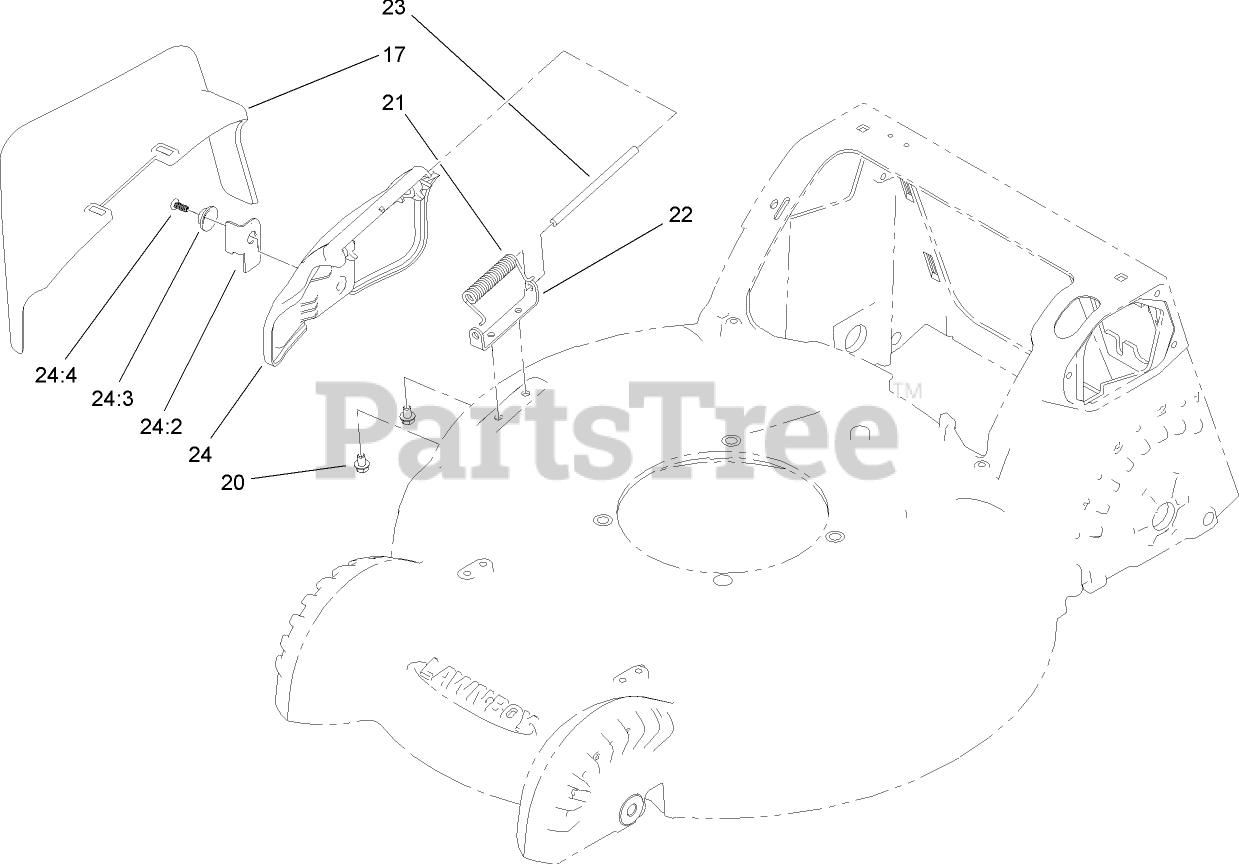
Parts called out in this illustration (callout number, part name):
17	CHUTE-DISCHARGE, SIDE
20	SCREW-HWH
21	SPRING-TORSION
22	BRACKET-COVER
23	ROD-COVER
24	DISCHARGE DOOR ASM
24:2	LATCH-DOOR
24:3	CAP-DOOR
24:4	SCREW-PLASTITE
